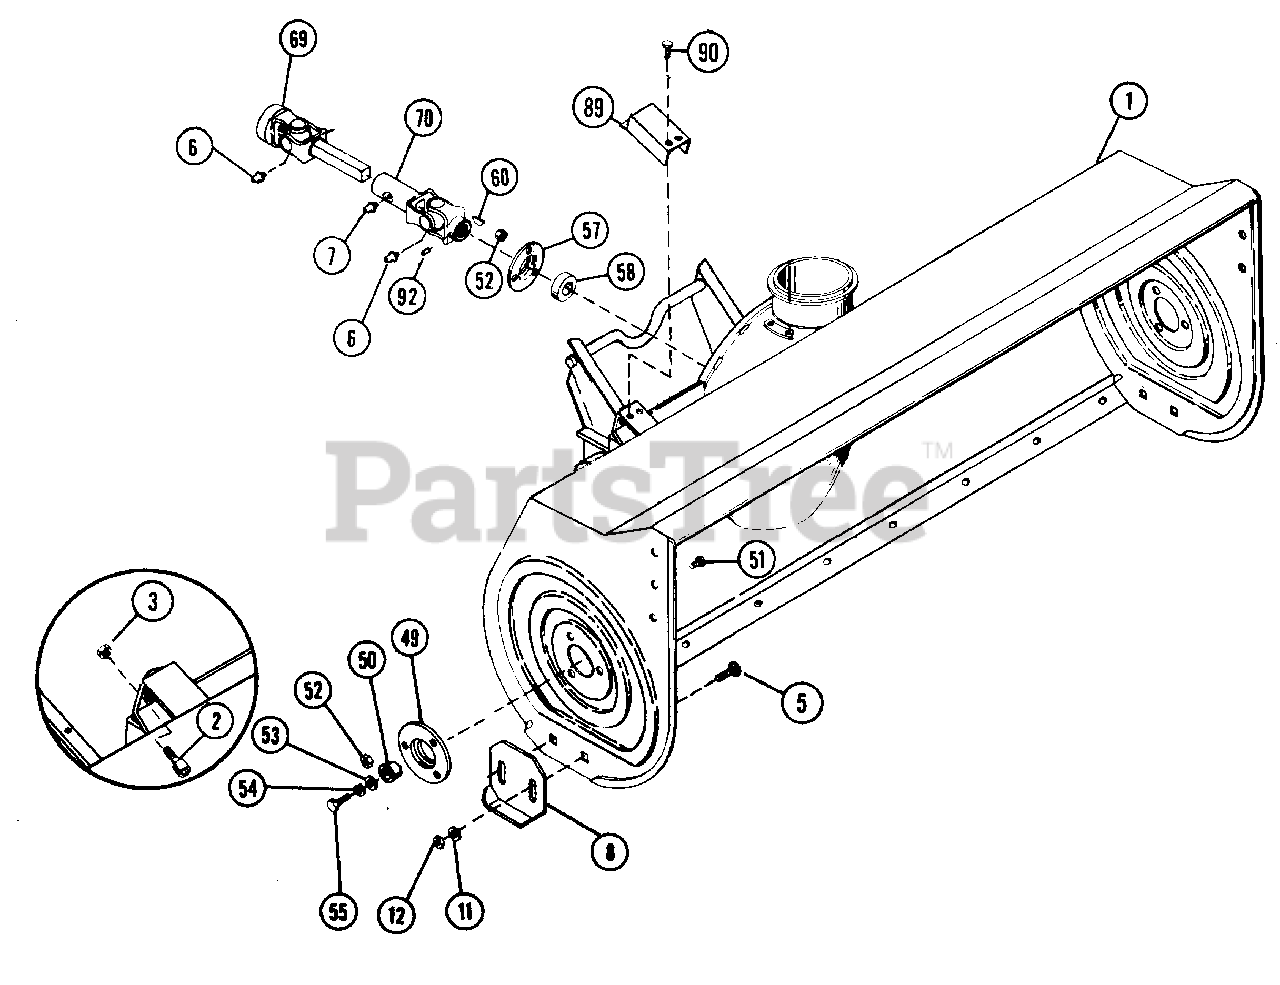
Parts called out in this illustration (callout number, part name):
1	40" SNO THRO HOUSING
1	48" SNO THRO HOUSING
2	SCREW, 10-24X.375 CAP
3	NUT, LOCK 10-24
5	BOLT, CARRIAGE 3/8-16X.75
8	RUNNER, SKID SHOE
11	WASHER, FLAT .406X.812X.065
12	NUT, LOCK 3/8-16
49	SUPPORT, BEARING
50	BUSHING, FLANGE 1X1.12X.625
51	BOLT, RIB NECK 1/4-20X.5
52	NUT, LOCK 1/4-20
53	WASHER, FLAT .515X1.441X.1
54	WASHER, LOCK 3/8 SP. HEAVY
55	BOLT, HEX 1/2-13X1
57	BEARING, FLANGE
58	BEARING, BALL
60	KEY, WOODRUFF 3/16X7/8 HRD #11
69	SHAFT, PROP. SQ. BAR
70	U-JOINT, FEMALE
90	BOLT, HEX 1/4-20X.50
92	SCREW, SET 3/8-16X.375
